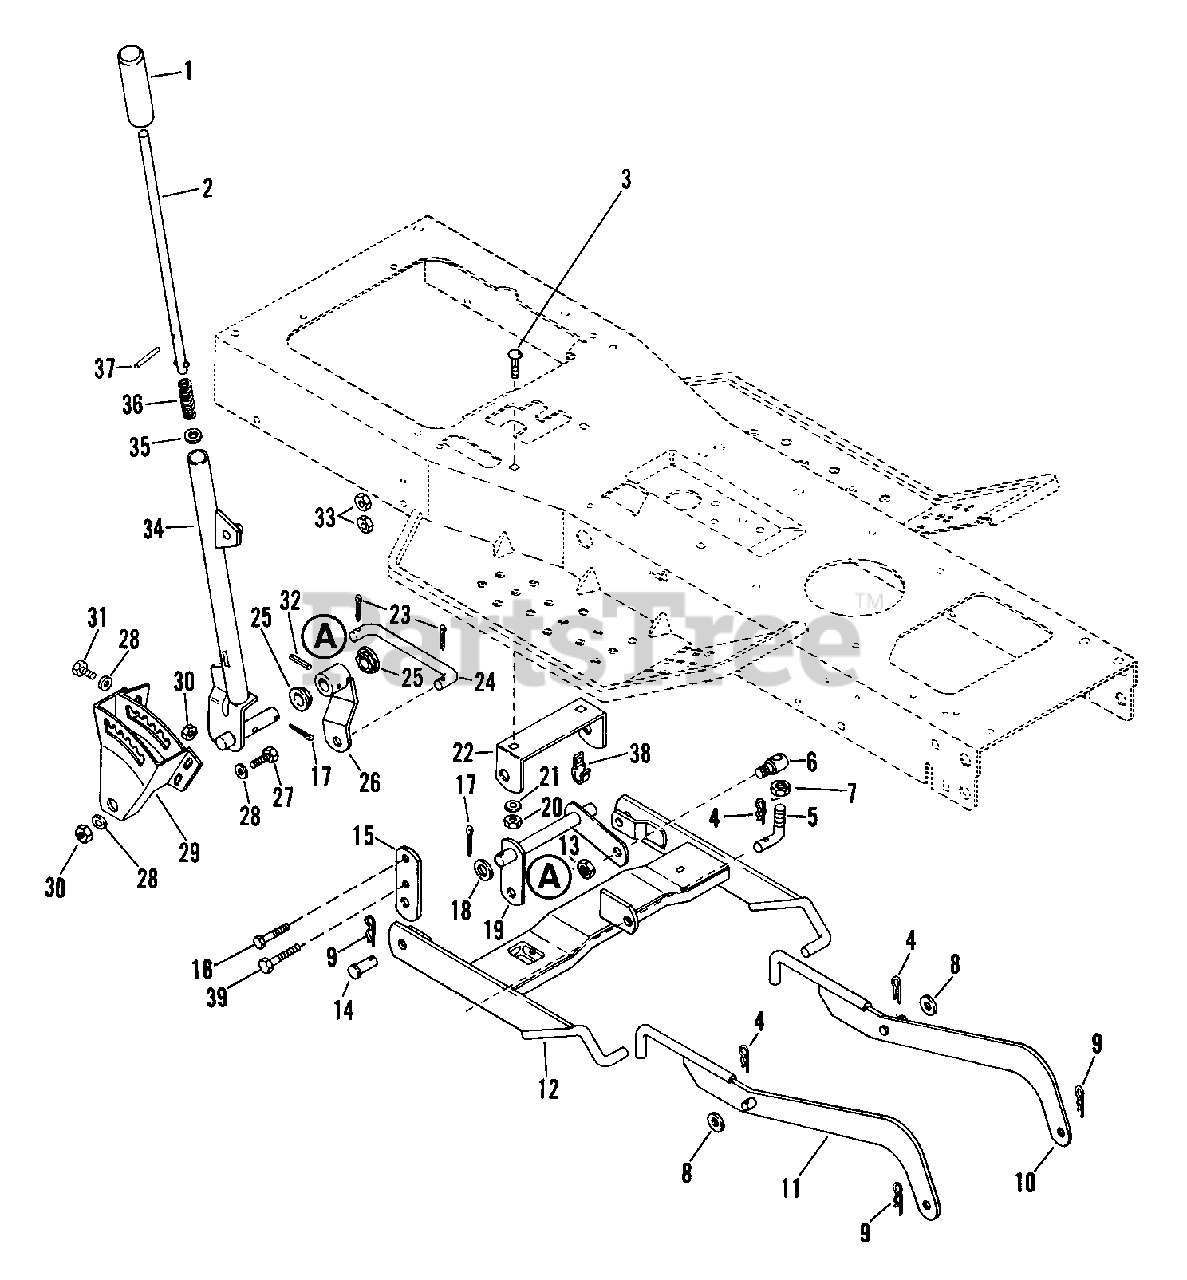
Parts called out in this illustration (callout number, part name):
2	PLUNGER ROD
3	BLT-RDHDSQNK .38-16X.75 SHT PL
4	PIN-HAIR INT .08X.38X1.42 YWZC
5	ADJUSTMENT LINK
6	ROD END
7	NUT-JAM .50-13 PL
8	WSHR-FL-STL .531X1.062X.095 PL
9	PIN-HAIR INT .09X.188 PL
10	LEFT HANGER
10	HANGER-LH
11	RIGHT HANGER
11	HANGER-RH
12	REAR HANGER
13	NUT-LK-CTR .50-13
14	PIN-CLEV .494X1.25 YWZC
15	HANGER BRACKET
16	BLT-HEX .38-16X.75 PL GR5
17	PIN-COTR .12X1.50 PL
18	WSHR-FL-STL .754X1.125X.062 PL
19	CENTER LIFT LEVER
20	NUT-HEX .375-16
21	WSHR-LK .375X.094 MED PL
22	CENTER LIFT BRACKET
23	PIN-COTR .12X1.0 PL
24	LIFT LINK
25	FLANGE BUSHING
26	LIFT ARM
27	BLT-HEX .31-18X1.25 PL GR5
28	WSHR-FL-STL .323X.625X.062 PL
29	LIFT QUADRANT
30	NUT-LK-TOP .312-18 GR C PL
31	BLT-HEX .31-18X.75 PL GR5
32	PIN-GRV .250X1.25 TP A
33	NUT-LK TOP .375-16 GR C YWZC
34	LIFT HANDLE
35	WSHR-FL-STL .458X.750X.06 PL
36	SG-COMP .048X.59X2.06 WLD9
37	PIN-ROLL .250X1.75
38	J-CLAMP
39	BLT-HEX .38-16X1.00 PL GR5
